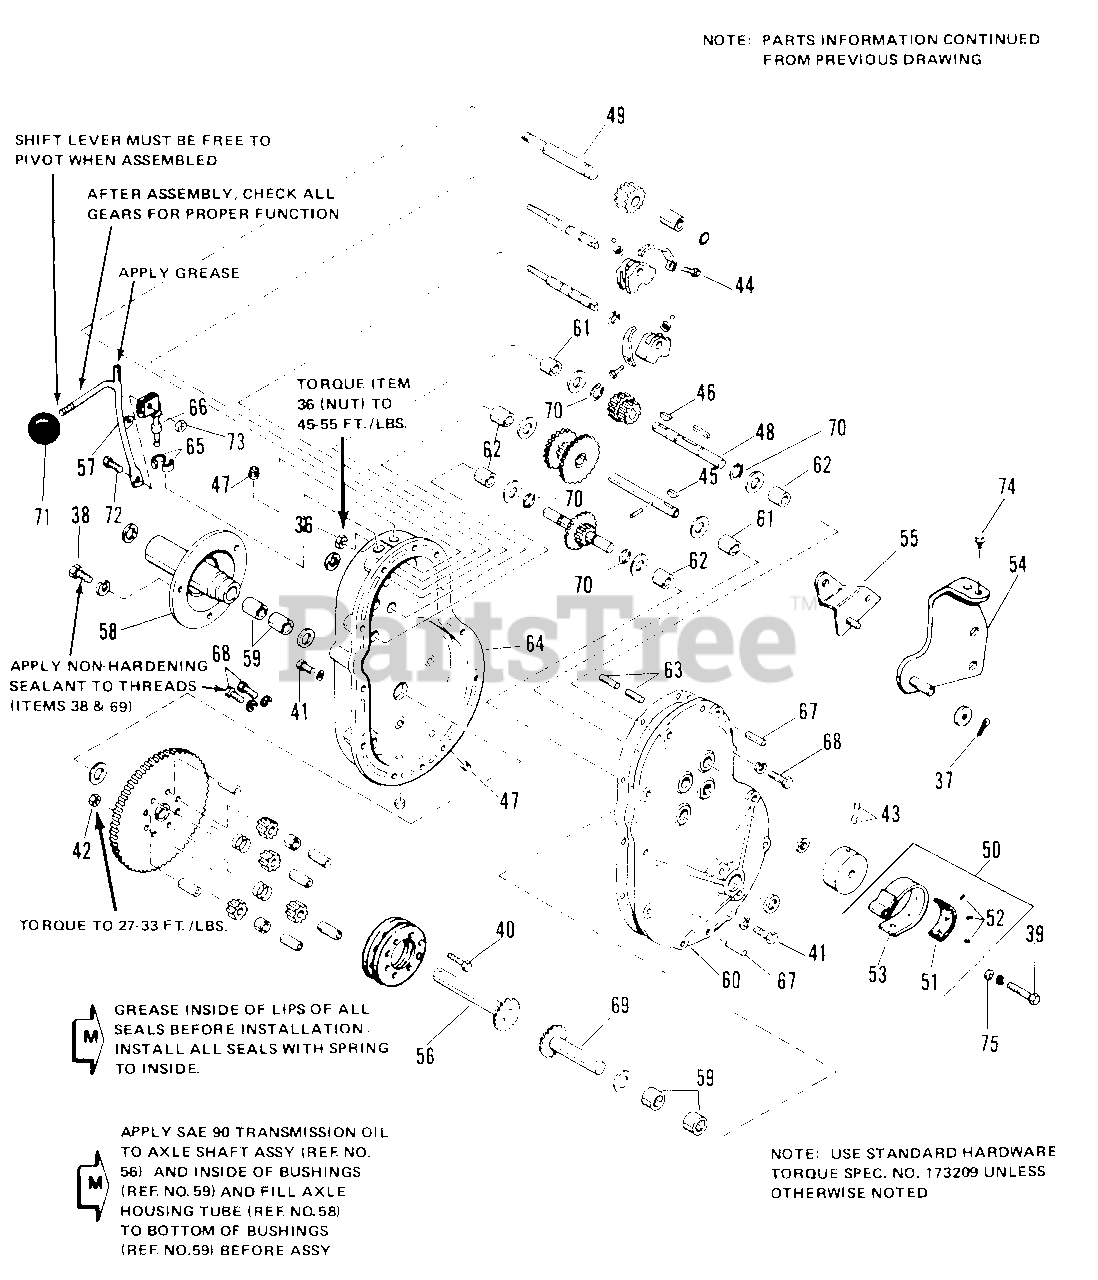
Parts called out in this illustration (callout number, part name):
36	NUT, Hex, 7/16-14
37	PIN, Cotter, 1/4 x 3/4
38	CAPSCREW, Hex Hd., 3/8-16 x 7/8
39	CAPSCREW, Hex Hd., 5/16-18 x 1-1/2
40	CAPSCREW, Hex Hd., 3/8-16 x 2-1/2
41	CAPSCREW, Hex Hd., 5/16-18 x 1-1/4
42	NUT, Flange, Lock, 3/8-16
43	SCREW, Set Hex Skt., 5/16-18 x 5/16
44	SCREW, Hex Washer Hd., 5/16-18 x 5/16
45	KEY, Hi Pro, 5/32 x 5/8
46	KEY, Hi Pro, 3/16 x 3/4
47	PIPE, Bushing, 3/4
48	SHAFT, Input
49	SHAFT, Reverse Pinion
50	BAND ASSY., Brake
51	LINING, Brake
52	RIVET, Tubular, 3/16 x 1/4
53	BAND, Brake
54	SUPPORT ASSY., Transmission
55	IDLER LEVER ASSY
56	AXLE ASSY., R.H. (6008)
56	AXLE ASSY., R.H. (6011)(03566)
57	ROD ASSY., Shift (6008)
57	ROD ASSY., Shift (6011)(03566)
58	HOUSING & BEARING ASSY., Axle (6008)
58	HOUSING & BEARING ASSY., Axle (6011)(03566)
59	BEARING, Roller (6008)
59	BEARING, Roller (6011)(03566)
60	COVER ASSY., Gear Case (Includes Ref. No. 59-63)(6008)
60	COVER ASSY., Gear Case (Includes Ref. No. 59-63)(6011)(03566)
62	BEARING, Roller
63	PIN, SUB-ASSY., Roll
64	GEAR CASE SUB-ASSY (6008) (Includes Ref. No. 61, 62, 66, 67)
64	GEAR CASE SUB-ASSY (6011)
66	ROD ASSY., Shift (6008)(03566)
66	ROD ASSY., Shift (6011)
67	PIN, Spring, 3/8 x 1
68	CAPSCREW, Hex Hd., 3/8-16 x 3/4
69	AXLE ASSY., L.H. (6008)(03566)
69	AXLE ASSY., L.H. (6011)
70	RING, Retaining
72	CAPSCREW, Hex, 1/4-20 x 1
73	LOCKNUT, 1/4-20
74	SCREW, Taptite, 5/16-18 x 5/8
75	WASHER, Plain, 5/16
